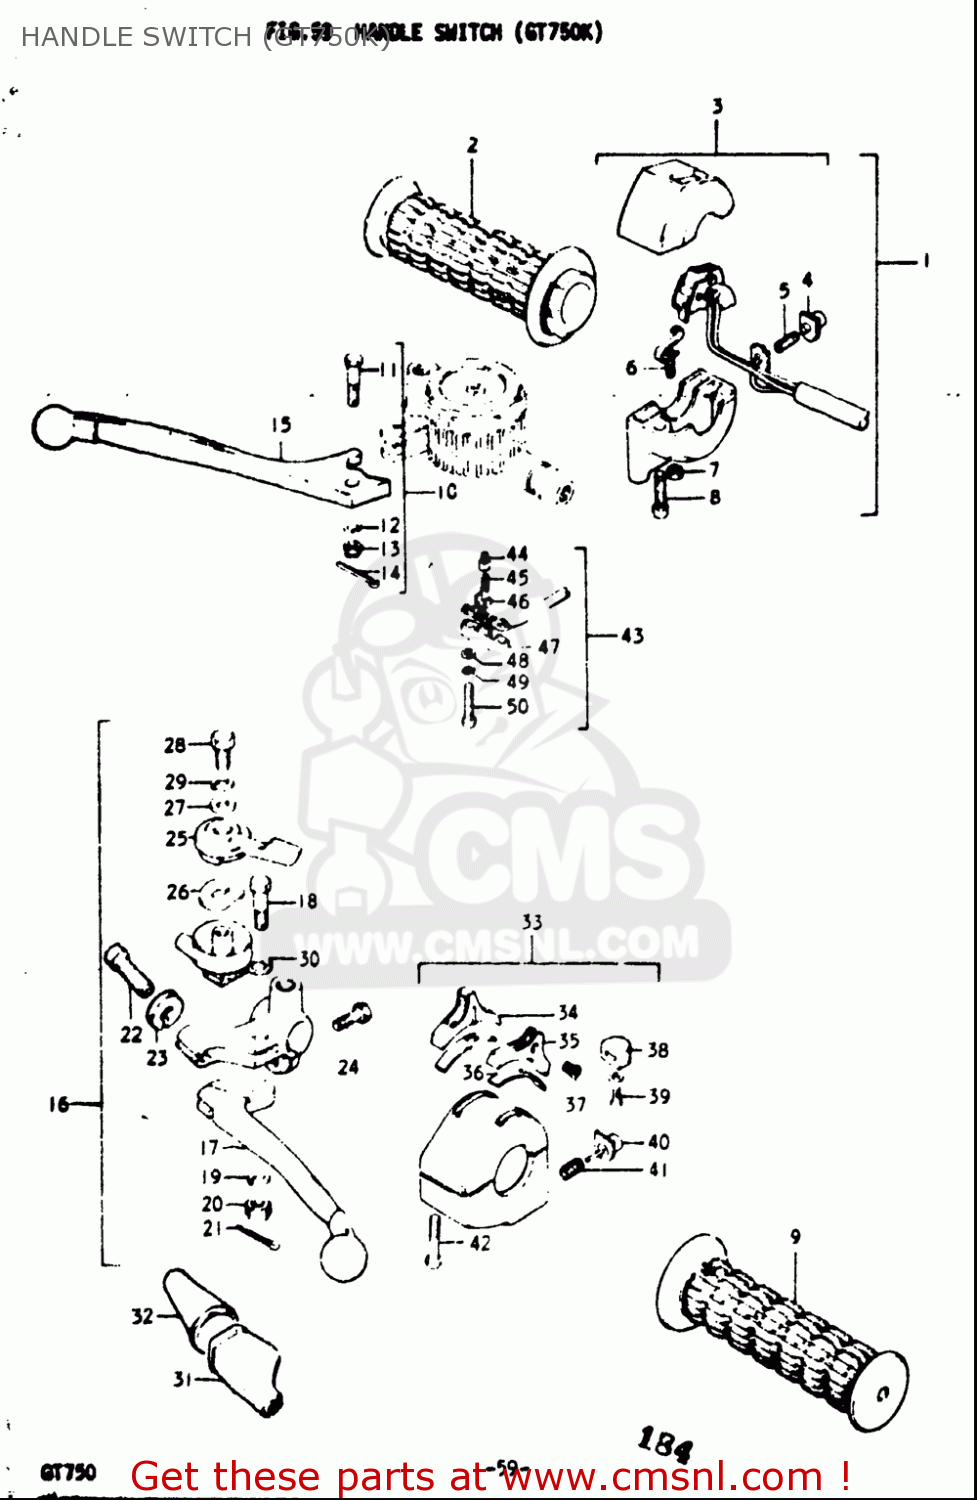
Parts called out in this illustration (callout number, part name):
1	GRIP ASSY,THROTTLE
2	GRIP,THROTTLE
4	BUTTON
5	SPRING
6	ADJUSTER, THROTTLE
7	NUT
8	SCREW
9	GRIP
11	BOLT
12	WASHER,LOCK
13	NUT,LEVER FITTNG
14	PIN 16X20
15	LEVER,BRAKE
17	LEVER,CLUTCH
18	BOLT,LEVER PIVOT
19	WASHER,LOCK
20	NUT,LEVER FITTNG
21	PIN 16X20
22	ADJUSTER,CABLE
23	NUT,CABLE ADJUSTER
24	BOLT
25	LEVER
26	WASHER,ADJUSTER
27	WASHER(6.5X16X1)
28	BOLT
29	WASHER,LOCK
31	COVER,CLUTCH LEVER
32	BOOT,CLUTCH CABLE
34	KNOB
35	KNOB
36	PLATE,SWITCH KNOB
37	SCREW
39	SCREW
40	BUTTON,HORN
41	SPRING,BUTTON
42	SCREW
43	SWITCH ASSY,STOP
44	CONTACT,SWITCH
45	CONTACT,SWITCH
46	CONTACT,SWITCH
47	COVER,FR BK TERMINAL BASE
48	WASHER
49	WASHER,LOCK
50	SCREW
